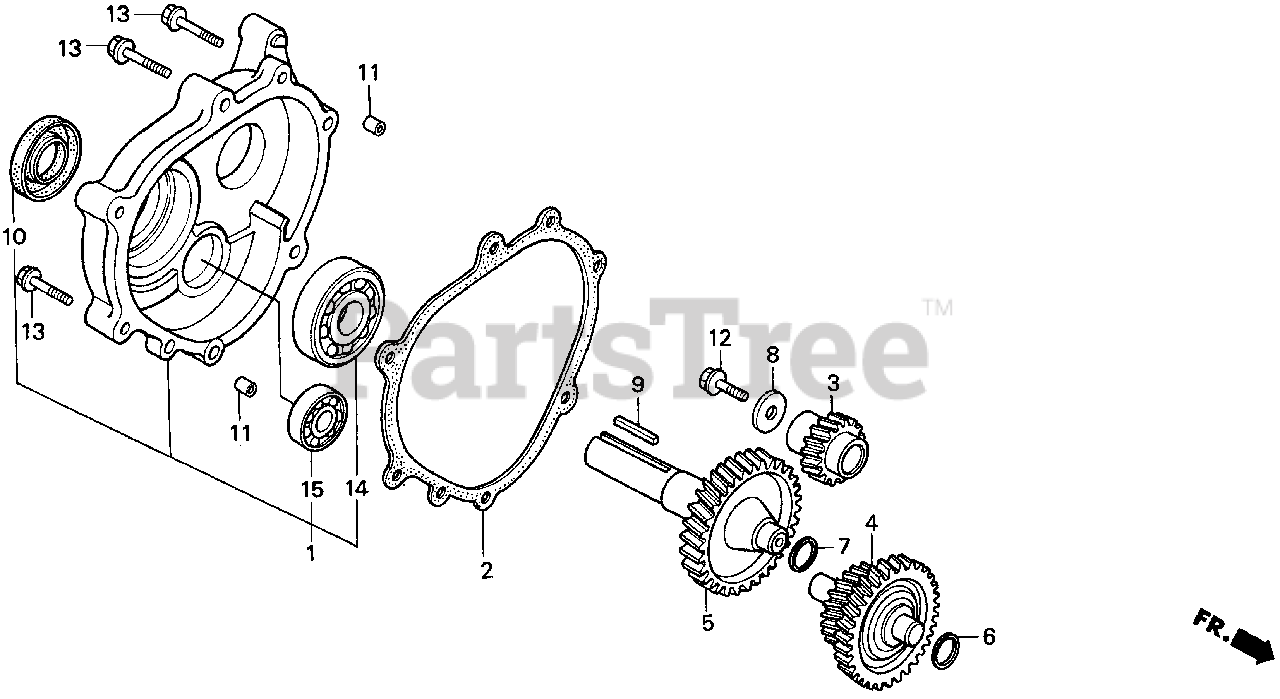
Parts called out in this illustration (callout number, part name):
1	COVER ASSY., REDUCTION CASE
2	GASKET, CHAIN CASE COVER
3	GEAR, PRIMARY DRIVE (17T)
4	COUNTERSHAFT
5	SHAFT, P.T.O. (H-TYPE)
6	SHIM A
7	SHIM B
8	WASHER (8MM)
9	KEY (6.3X6.3X43)
10	OIL SEAL (30X46X8)
11	PIN A, DOWEL (8X14)
12	BOLT, FLANGE (8X25)
13	BOLT, FLANGE (8X40)
14	BEARING, RADIAL BALL (6206)
15	BEARING, RADIAL BALL (6302)
